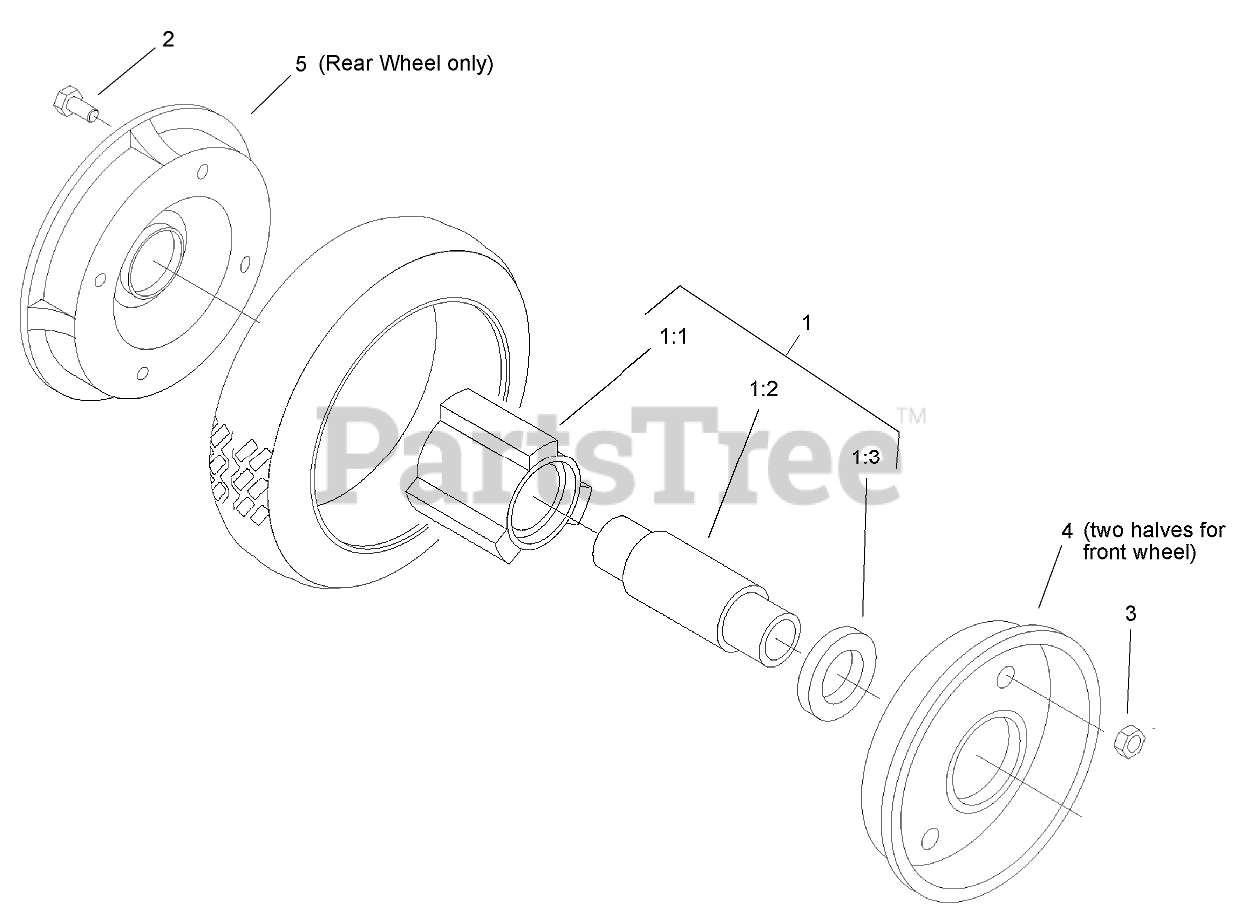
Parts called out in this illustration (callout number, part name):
1	HUB and BEARING ASM
1:1	HUB-BEARING
1:2	SPACER-BEARING
1:3	BEARING-WHEEL
2	SCREW-HH
3	NUT-LOCK, NI
4	PLATE-WHEEL, HALF
5	WHEEL HALF AND GEAR ASM
